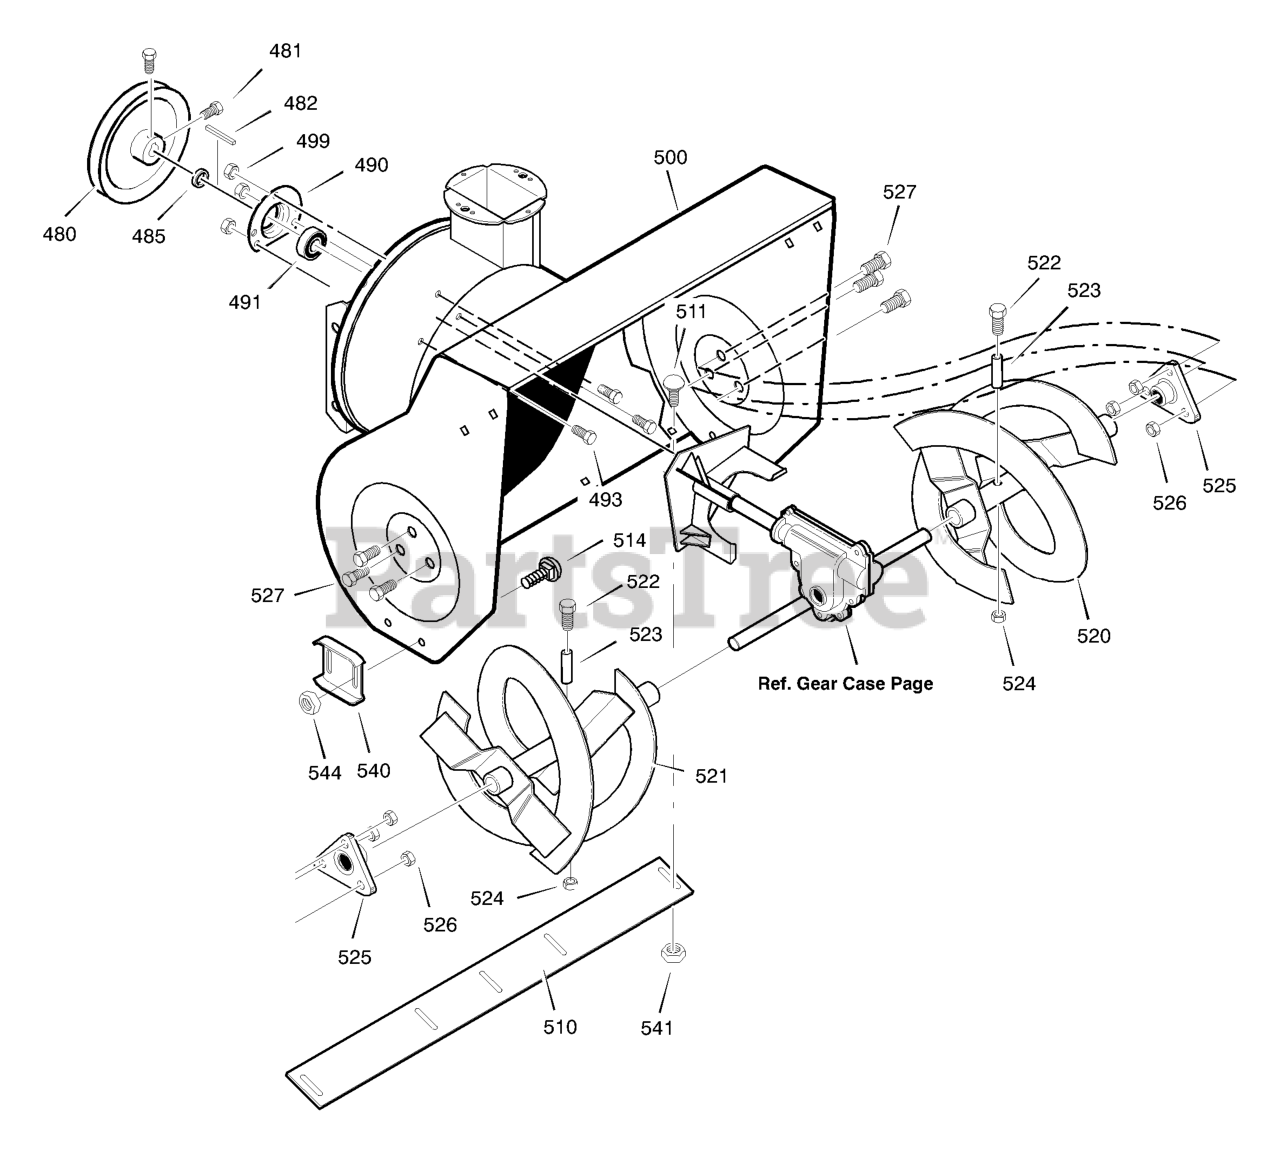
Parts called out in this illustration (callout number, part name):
480	PULLEY, 4L 6.12X .67
481	SCREW, 5/16-18 x 0.63
482	KEY, SQUARE 3/16 X 3/4
485	SPACER, FRICTION PULLEY
490	RETAINER, BALL BRNG
491	BEARING, BALL
493	BOLT, HEX 5/16-18X .50
499	NUT, 5/16-18 HEXWDFLLK
500	HOUSING, ASSY
510	BLADE, SCRAPER
511	BOLT, 1/4-20X.75
514	NUT, 1/4-20
520	AUGER, ASSY, LH
521	AUGER, ASSY, RH
522	SCREW, 1/4-20X1.75
523	SPACER, SLEEVE
524	NUT, 1/4-20
525	BEARING,FLANGE
526	NUT, 5/16-18
527	SCREW, 5/16-18 x 0.75
540	SKID, HEIGHT ADJUST
541	BOLT, 5/16-18 X .75
544	NUT, 5/16-18
